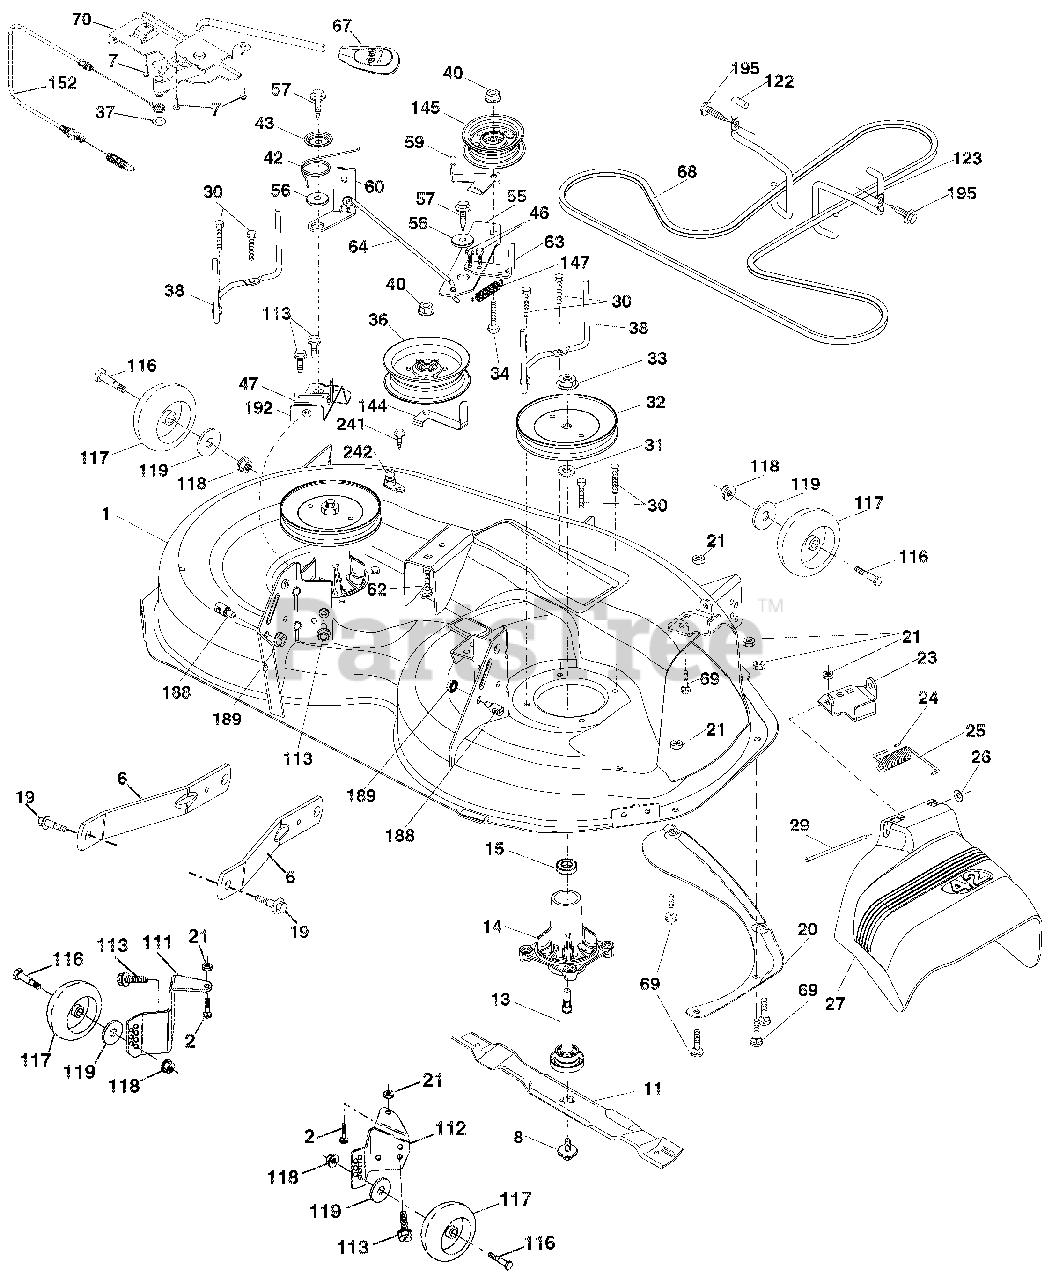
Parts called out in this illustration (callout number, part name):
1	DECK.PNT.WELDMENT.42"
1	DECK.SVC.46"HP.CC.4GWB.TEX.422
6	ARM.SUSPENSION.MOWER.REAR.LD
8	BOLT/WASHER ASM.7/16-20.UNF
11	BLADE.MOWER.42"HI LIFT PREMIUM
11	Blade 42SP" 3N1
11	Blade 42SP" 3N1 Premium
11	BLADE, HUSQ MULCH KIT
11	Blade Mulching 42 Premium (Fo
13	SHAFT ASM.MNDRL.N/GREASEABLE38
14	HOUSING.MANDREL.4PT.SERVICE
15	BEARING.BALL.MANDREL
19	BOLT.SHOULDER
20	BAFFLE.VORTEX.42.STD/HEAVY DTY
21	Nut, Hex, Crownlock 5/16-18
23	BRACKET.DEFLECTOR.38/42"2005
24	CAP.SLEEVE..80X.112.BLK.MOWER
25	SPRING.TORSION.DFL.38/42/46.GR
26	NUT.PUSH.PHOS.& OIL
27	SHIELD.DEFLECTOR.MOWER 42"BLK
29	ROD.HINGE.42/46"
30	SCREW.THD ROLL.DOD PT.HEX
31	WASHER.SPACER.MANDREL
32	PULLEY.MANDREL.5.438 PD.42"
32	MANDREL ASM.SUB.N-GRS.4 BOLT
32	PULLEY/NUT/WASHER AND BLADE BOLT/WASHERS NOT INCLUDED)
33	NUT.FLANGE.LOCK.TOP
34	BOLT.CARR.SH.3/8-16X1-1/2.GR5
36	PULLEY.IDLER.4.50.RAW
37	WASHER.13/32 X 13/16 X 16 GA.
38	KEEPER.BELT.LH.MANDREL.42/46"
40	Nut, Hex, Flangelock 3/8-16
42	SPRING.TORSION.BRAKE
43	SPRING.TORSION.RETAINER
46	SCREW.THD.ROLL.1/4-20 X 5/8
47	BRACKET.CLUTCH.CABLE
55	IDLER.ARM
56	SPACER.RETAINER
57	SCREW.3/8-16X1.SMGML.TAP/R.BLK
59	GUARD.TUV.IDLER
60	ARM.BRAKE.MOWER.42"
62	BOLT.RD.HD.SQ.NK.3/8-16UNC X 2
63	ARM.BRAKE.MOWER
64	LINKAGE.BRAKE
67	HANDLE.CLUTCH.CABLE.LT TEX.428
68	BELT.DRIVE.100.97"
69	BOLT.RDHD.SQNK.5/16-18 X 5/8
70	CLUTCH ASM.MANUAL.LT.TEX
111	BRACKET WHEEL GAUGE LH
112	BRACKET WHEEL GAUGE RH
113	BOLT.5/16-18HEX.WHS.HD.LCKSERR
116	BOLT.SHLD."A"2.41."B"1.66
117	WHEEL.GAGE.HALF.SPOKED
118	Nut, Hex, Flangelock 3/8-16
119	Washer 3/8 x 7/8 x 14 Ga.
122	KEEPER.BELT.ENGINE.LH.LT.TEX
123	KEEPER.BELT.ENGINE.RH.LT.TEX
144	KEEPER.BELT.MOWER
145	PULLEY.IDLER 48"PRIMARY
147	SPRING.RETURN.DECK.38/46"
152	CABLE.CLUTCH.MANUAL.W/SPR.
188	STUD.FASTNER.W/'D'ANTI-ROTATIO
189	Nut, Lock Hex Flange 5/16-18 u
192	BRACKET.BRAKE.STAND.LH
195	SCREW.HEXWSH THDR3/8-16X3/4.BL
242	PORT WASHOUT
